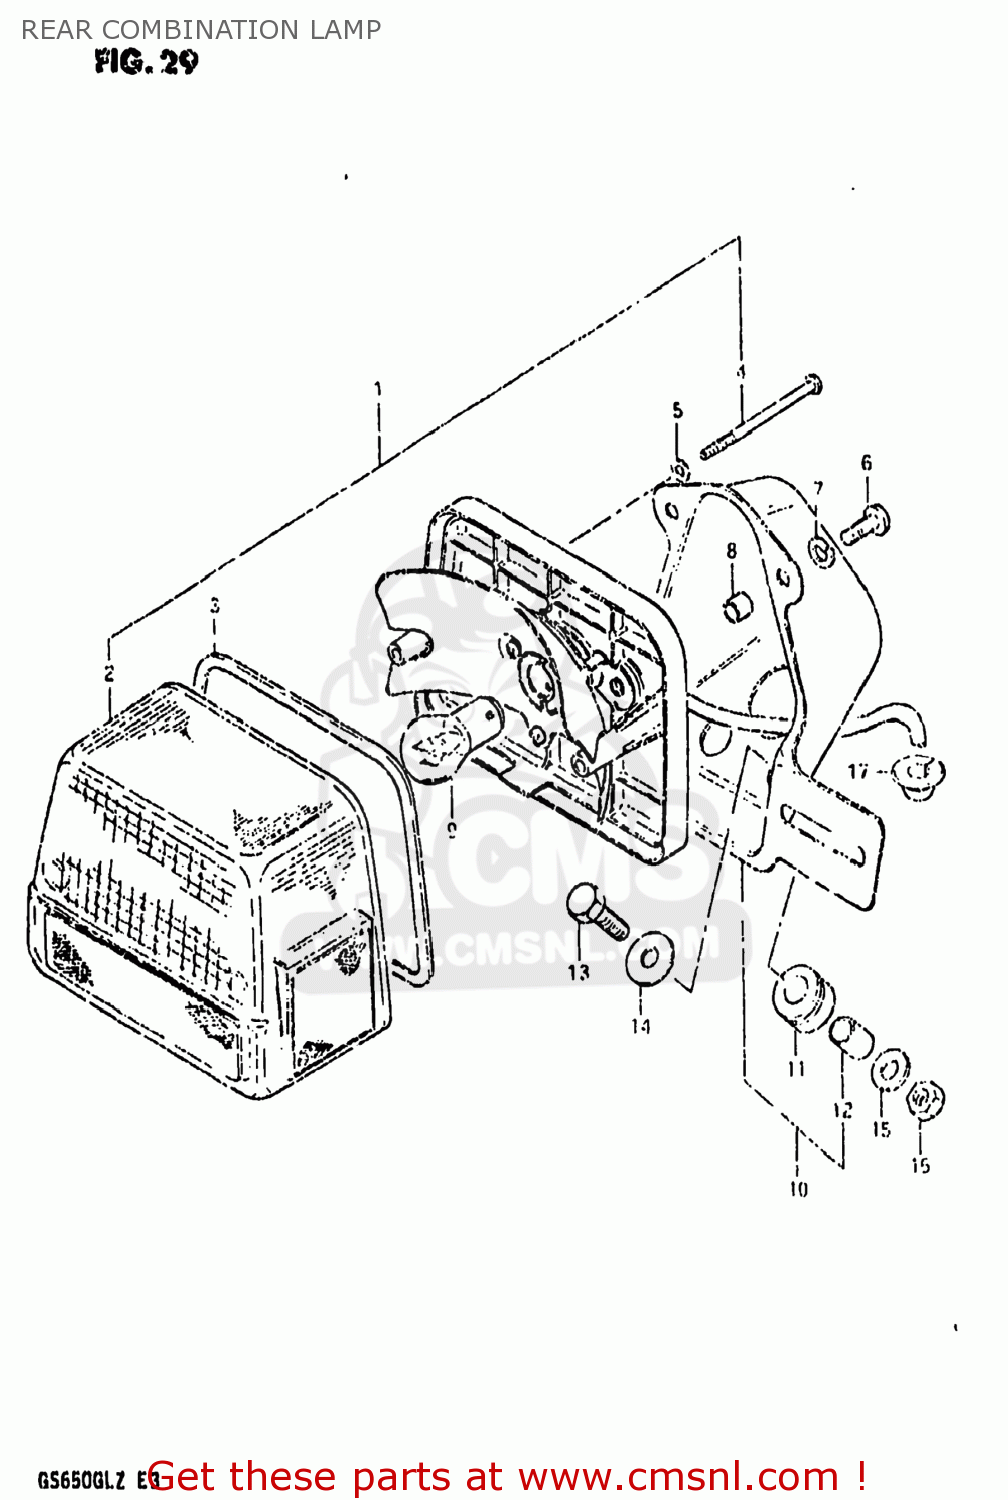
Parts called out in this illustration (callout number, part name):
1	LAMP UNIT,RR COMBNATION
2	LENS
3	GASKET (NAS)
4	SCREW
5	GASKET (NAS)
6	SCREW 6X12
7	LOCK WASHER
8	SPACER
9	BULB(12V23W)
10	BRACKET UNIT,TAIL LAMP
11	CUSHION
12	SPACER
13	BOLT
14	WASHER (6.5X20X1.2)
15	WASHER
16	GROMMET
